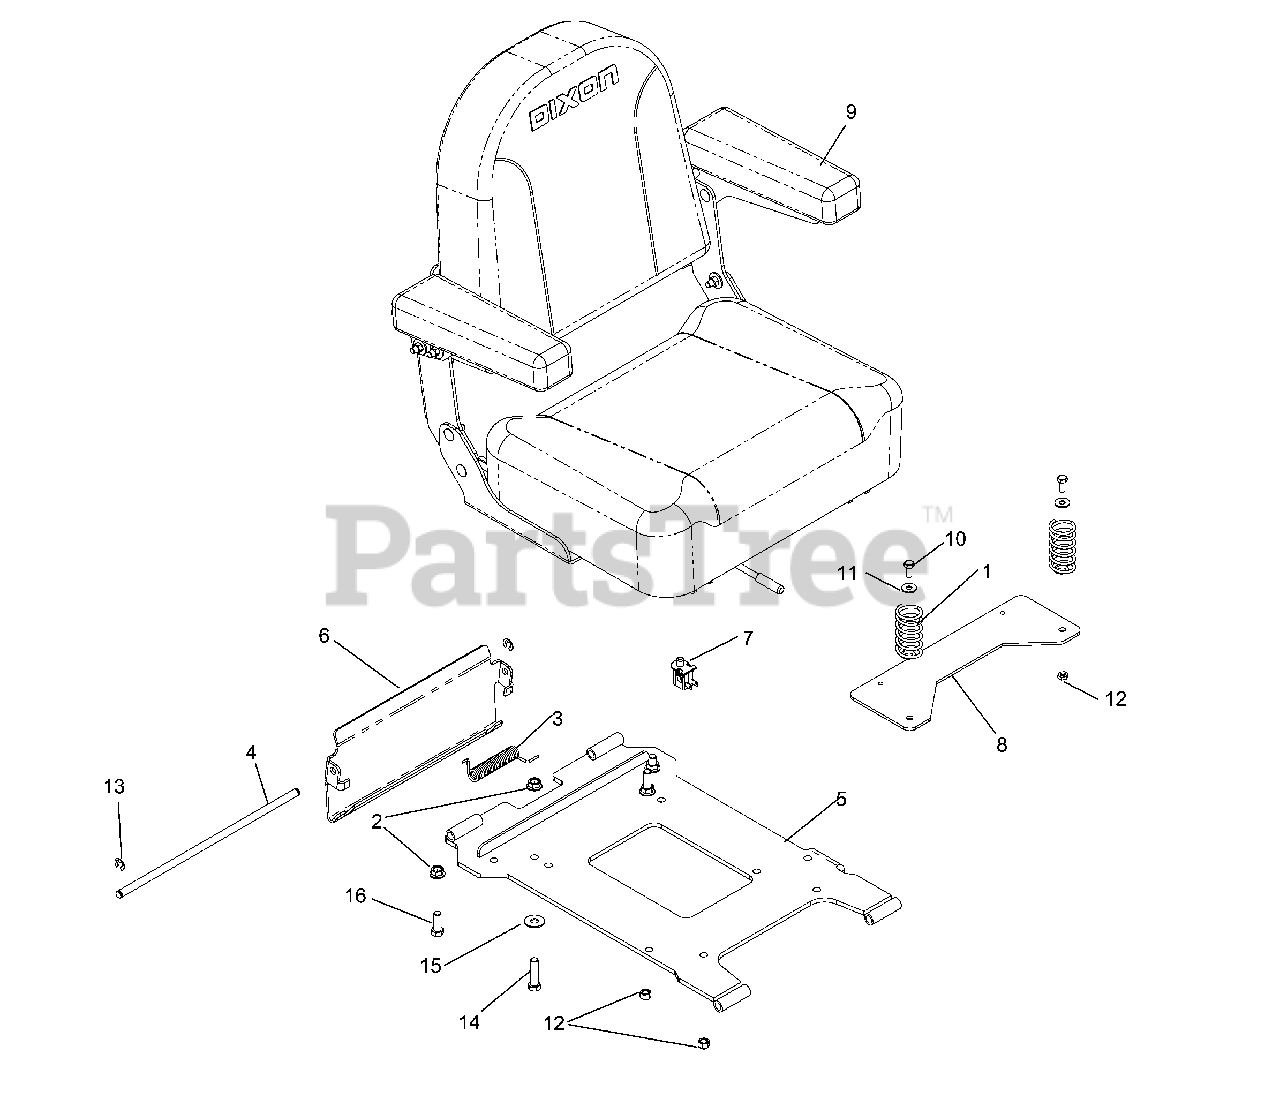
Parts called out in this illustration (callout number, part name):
1	SPRING, SEAT
2	NUT 3/8C WHIZ
3	TORSION SPRING (SEAT)
4	SEAT LATCH ROD
5	SEAT MOUNT W/DECAL
6	LATCH, SEAT
7	SEAT SWITCH
8	MOUNT, SPRING-SEAT, BLACK
9	SEAT ASM W/SLIDE
10	HCS 5/16C X 1
11	WASHER 5/16 FLAT
12	NUT 5/16 NYLOC
13	E RING 3/8"
14	TAP BOLT 3/8C X 1.5
15	WASHER 3/8 FLAT
16	HCS 3/8C X 1
